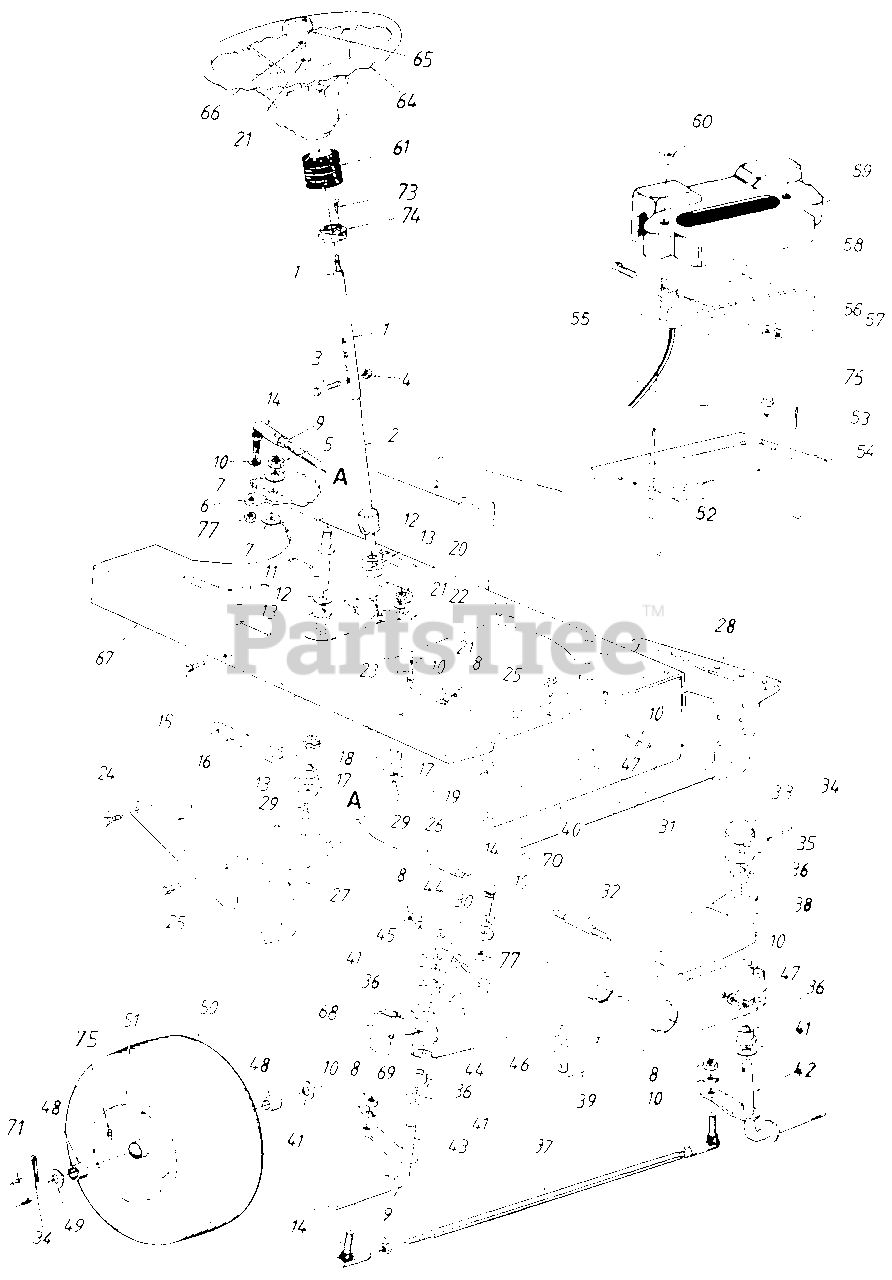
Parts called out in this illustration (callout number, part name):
1	Steering Column Ass'y.
2	Lower Steering Shaft
3	Hex Bolt 1/4-20 x 1.31" Lg.
4	Hex L-Nut 1/4-20 Thd.
5	Hex Jam Nut 5/8-18 Thd.
6	Steering Gear Segment
7	Bell-Wash. 5/8" I.D. x 1.25" O.D.
8	Hex Nut 3/8-24 Thd.
9	Hex Jam Nut 3/8-24 Thd.
10	L-Wash. 3/8" I.D.
11	Steering Gear Segment Shaft
12	Fl-Wash. .64" I.D. x 1.24" O.D.
13	Hex Flange Brg. .63" I.D.
14	Ball Joint Ass'y.
15	Hex Wash. Hd. TT-Tap Scr. 1/4-20 x .5" Lg.
16	Deck Idler Support Brkt.
17	Fl-Wash. .33" I.D. x 1.25" O.D.
18	Spacer .985" I.D. x 1.25" O.D.
19	L-Wash. 5/16" I.D.
20	Hex Nut 5/16-24 Thd.
21	Bell-Wash. .345" I.D. x.88" O.D.
24	Ribbed Neck Bolt 3/8-24 x .8" Lg.
25	Hex Wash. TT-Tap Scr. 5/16-18 x .62" Lg.
26	Steering Drag Link
27	Pivot Bar Side Plate - R.H.
28	Pivot Bar Side Plate - L.H.
29	Hex Bolt 5/16-18 x .62" Lg.
30	Steering Arm
31	Deck Connecting Rod
32	Pivot Bar Shld. Bolt 3/8-16 x 5/8" Lg.
33	Cap
34	Cotter Pin 5/32" Dia.
35	Flat Washer
36	Flange Brg. .757" I.D.
37	Tie Rod 20.25" Lg.
38	Pivot Bar Assy.
41	Fl-Wash. .76" I.D. x 1.49" O.D.
42	Front Axle Ass'y.- L.H.
43	Front Axle Ass'y.- R.H.
44	Bowed Washer
45	Spacer .755" I.D. x 1.25" O.D.
46	Hex Bolt 3/8-24 x 2.25" Lg.
47	Hex Nut 3/8-16 Thd.
48	Flange Brg. .75" I.D.
49	Fl-Wash. .71" I.D. x 1.5" O.D.
50	Wheel Ass'y. Comp.
51	Rim Only
52	Push Nut
53	Battery Hold Down Rod
56	L-Wash. 1/4" I.D.
57	Hex Nut 1/4-20 Thd.
58	Battery (275 Cold Crank Amps)
59	Battery Cover
60	Wing Nut Plastic 1/4-20 Thd.
61	Steering Bellow
64	Steering Wheel
65	Steering Wheel Cap
66	Hex L-Nut 5/16-24 Thd.
67	Lower Frame
68	Pivot Bar End Cap
69	Grease Fitting
70	Internal Cotter Pin
71	Hub Cap
75	Air Valve
76	Hex AB-Tap Scr. 1/4 x .62" Lg.
77	Hex Jam L-Nut 3/8-24 Thd.
